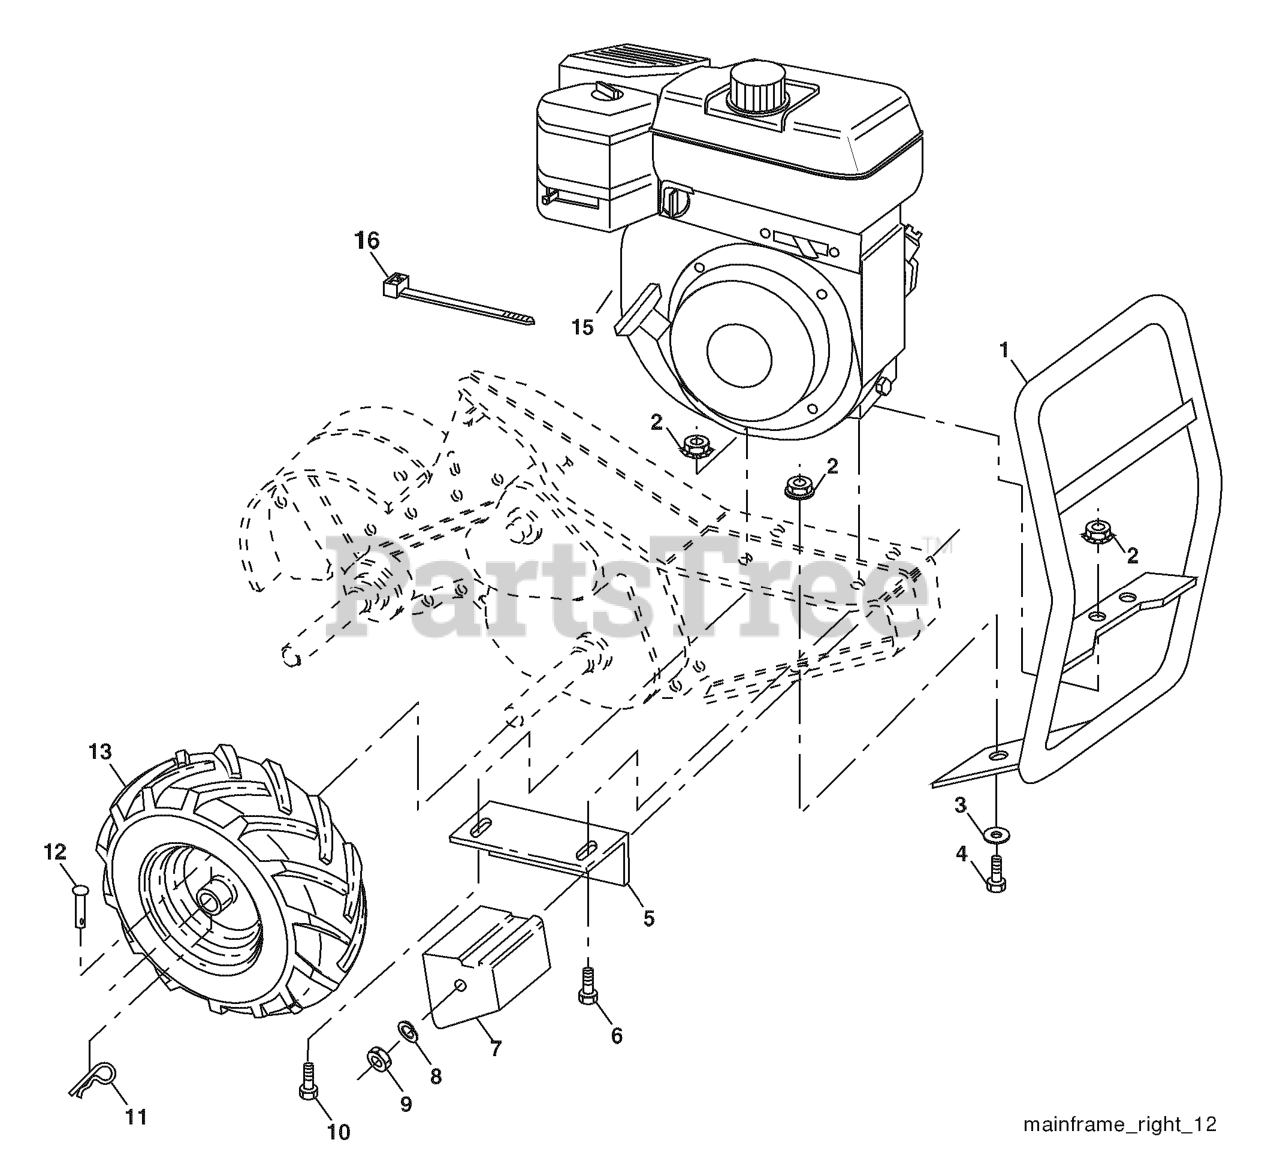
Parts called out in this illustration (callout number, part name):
1	RP.BUMPER.ASM.TILLER.
2	LOCKNUT-FLANGE 5/16-18
3	WASHER
4	BOLT
5	DNO BRACKET RH CRT
7	COUNTERWEIGHT, RH
8	WASHER, LOCK 3/8
9	NUT.HEX.3/8-16UNC
10	BOLT
11	RETAINER M
12	RIVET,DRILLED
13	TIRE.13X5-6.CHEVRON.TILLER
13	RIM.ASM.6".SILVER
13	VALVE STEM LT
16	TIE GUIDE
22	BOLT, HEX 5/16-18X1-3/4
